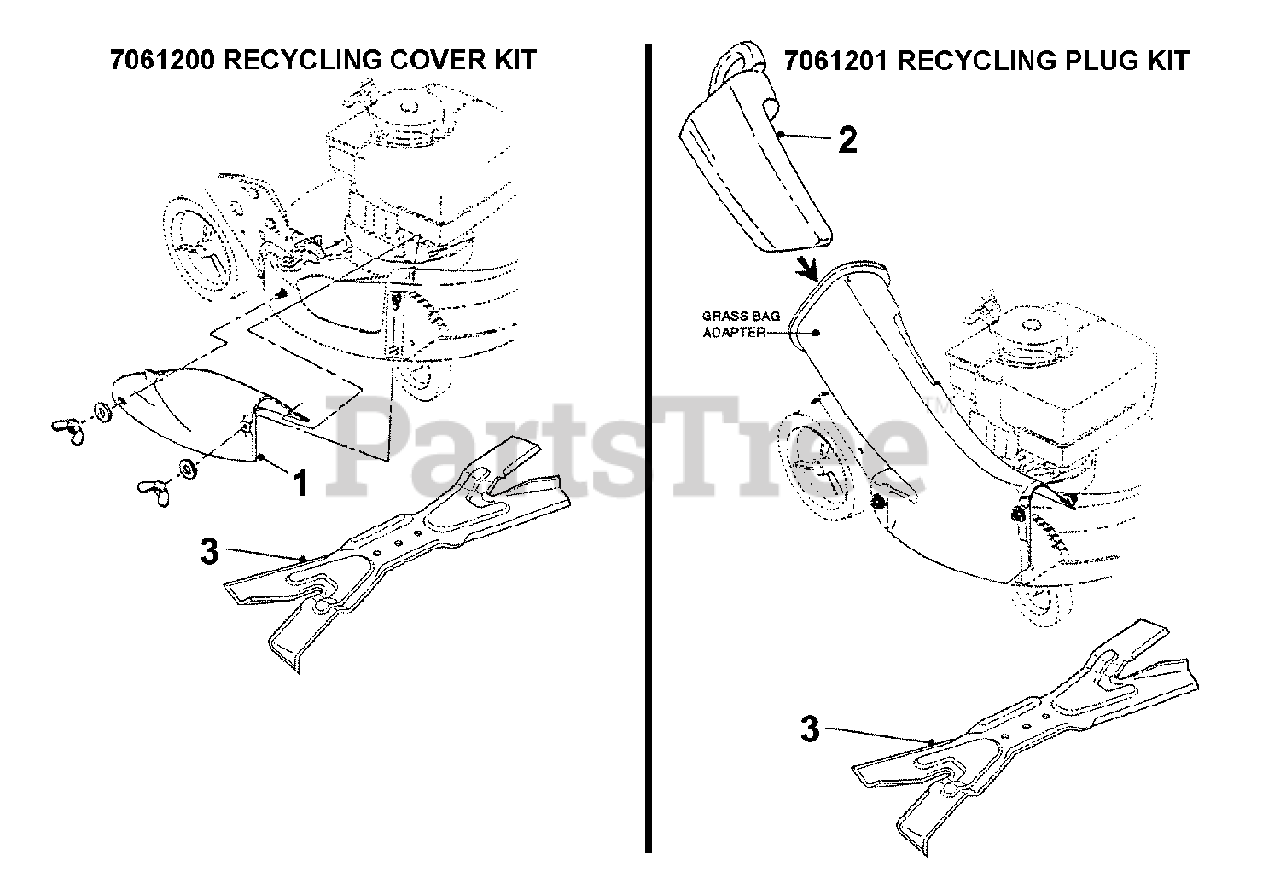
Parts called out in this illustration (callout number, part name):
1	COVER, 21" Deck
2	PLUG, Chute Adapter
3	BLADE, 21" Quad Edge Ninja
